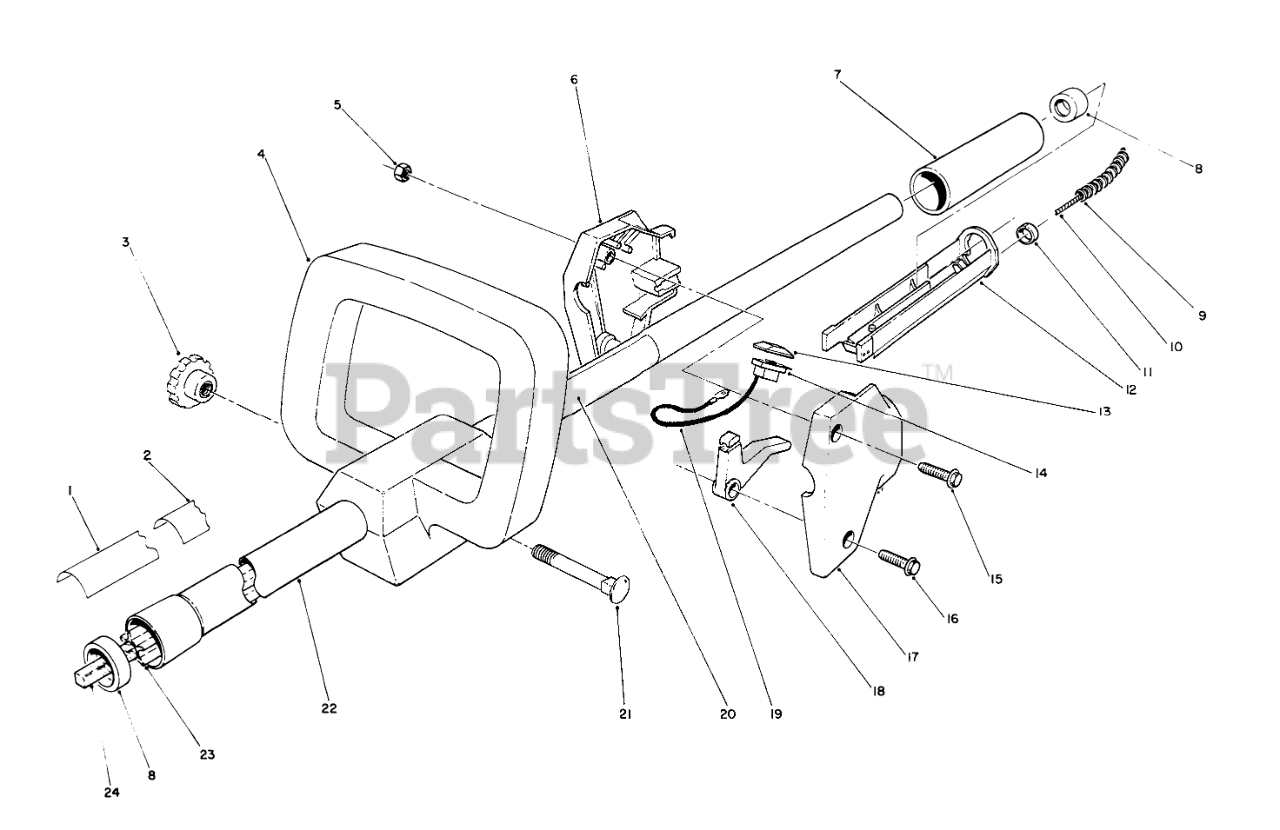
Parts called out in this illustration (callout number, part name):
1	DECAL - TC 3105
2	DECAL - WARNING
4	HANDLE SECONDARY
5	NUT-LOCK, NI
6	Switch
7	GRIP - RUBBER
8	CASING RETAINER
9	CABLE COVER
10	THROTTLE CABLE
11	RING FITTING
12	Trough
13	SWITCH COVER
14	SWITCH
16	SCREW-SHOULDER
17	LH HOUSING
18	THROTTLE LEVER
19	WIRE ASM
20	DECAL-INSTRUCTION
21	BOLT-CARRIAGE
22	SHAFT HOUSING TUBE
23	SHAFT SPACER
24	DRIVE SHAFT
